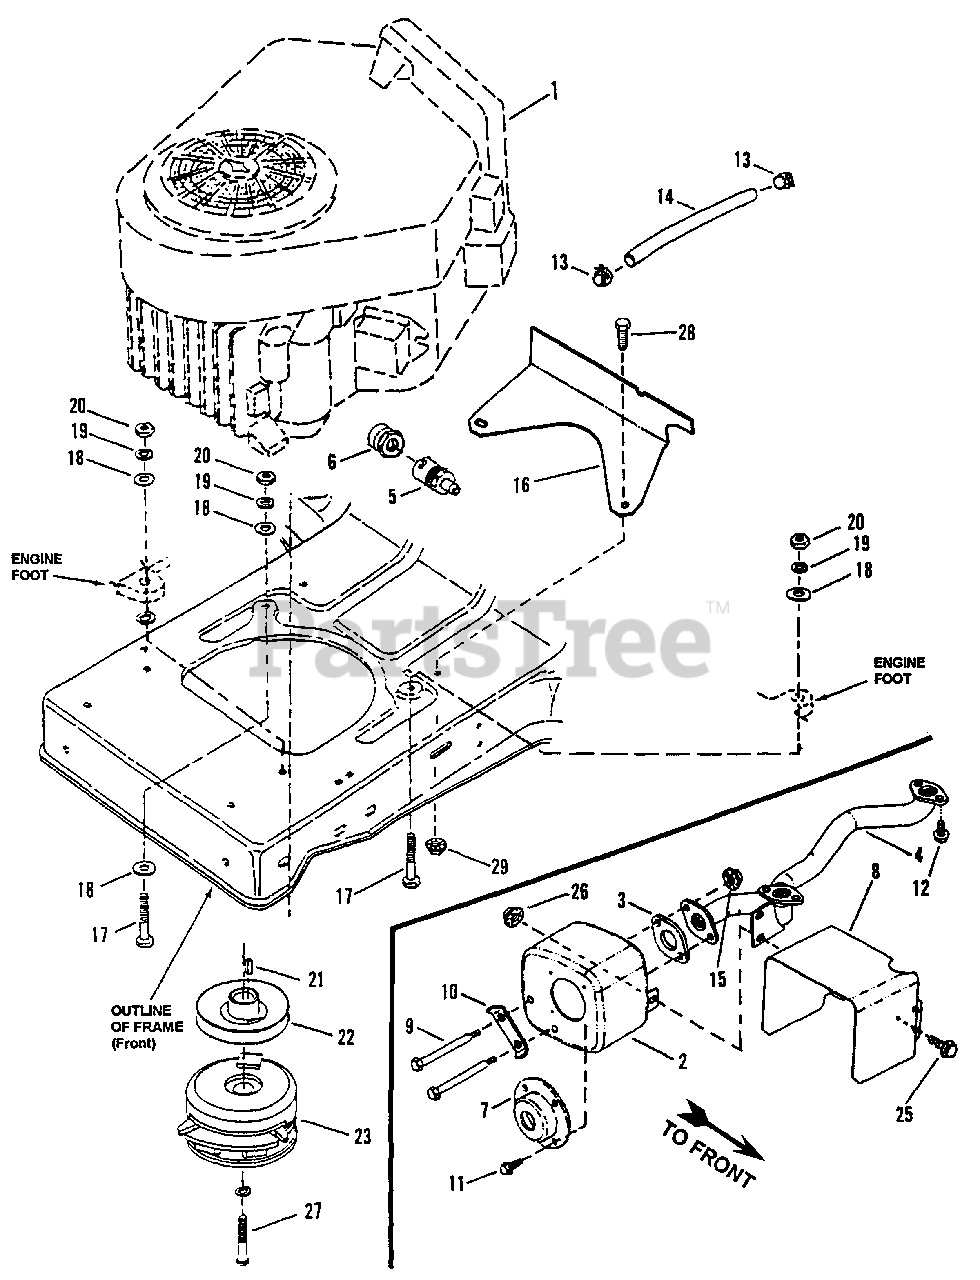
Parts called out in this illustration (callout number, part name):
2	MUFFLER
3	GASKET, Muffler/Exhaust
4	MANIFOLD, Exhaust
5	ASSEMBLY, Oil Valve Drain
6	EXTENSION, Oil Drain
7	DEFLECTOR, Exhaust
8	SHIELD, Muffler Heat
9	BOLT, 5/16-18 x 3-1/2 Shoulder Hex Head
10	LOCK, Screw
11	SCREW, #8-18 x 1/2 Self Tapping
12	SCREW, 5/16-18 x 1/2" Hex Washer Face Self Tapping
13	CLAMP, Fuel Line
14	LINE, Fuel, 16 Long
15	NUT, 5/16-18 Hex Flanged Lock Grade 5
16	SHIELD, Heat
17	SCREW, 5/16-18 x 1-3/4 Hex Head Cap Grade 5
18	WASHER, 5/16 Flat Grade 5
19	WASHER, 5/16 Split Lock
20	NUT, 5/16-18 Hex Grade 5 or B
21	KEY, 1/4 x 1/4 x 3/4 Square
22	PULLEY, Traction Drive
23	CLUTCH/BRAKE
25	CAPSCREW, 1/4-20 x 5/8" Hex Head Grade 5
26	NUT, 1/4 -20 Hex Flanged Lock Grade 5
27	SCREW, 7/16-20 x 2-1/2 Hex Head Cap Special Grade 5
28	CAPSCREW, 5/16-18 x 1 Hex Head Grade 2
29	NUT, 5/16-18 Hex Flange Lock Grade 5
